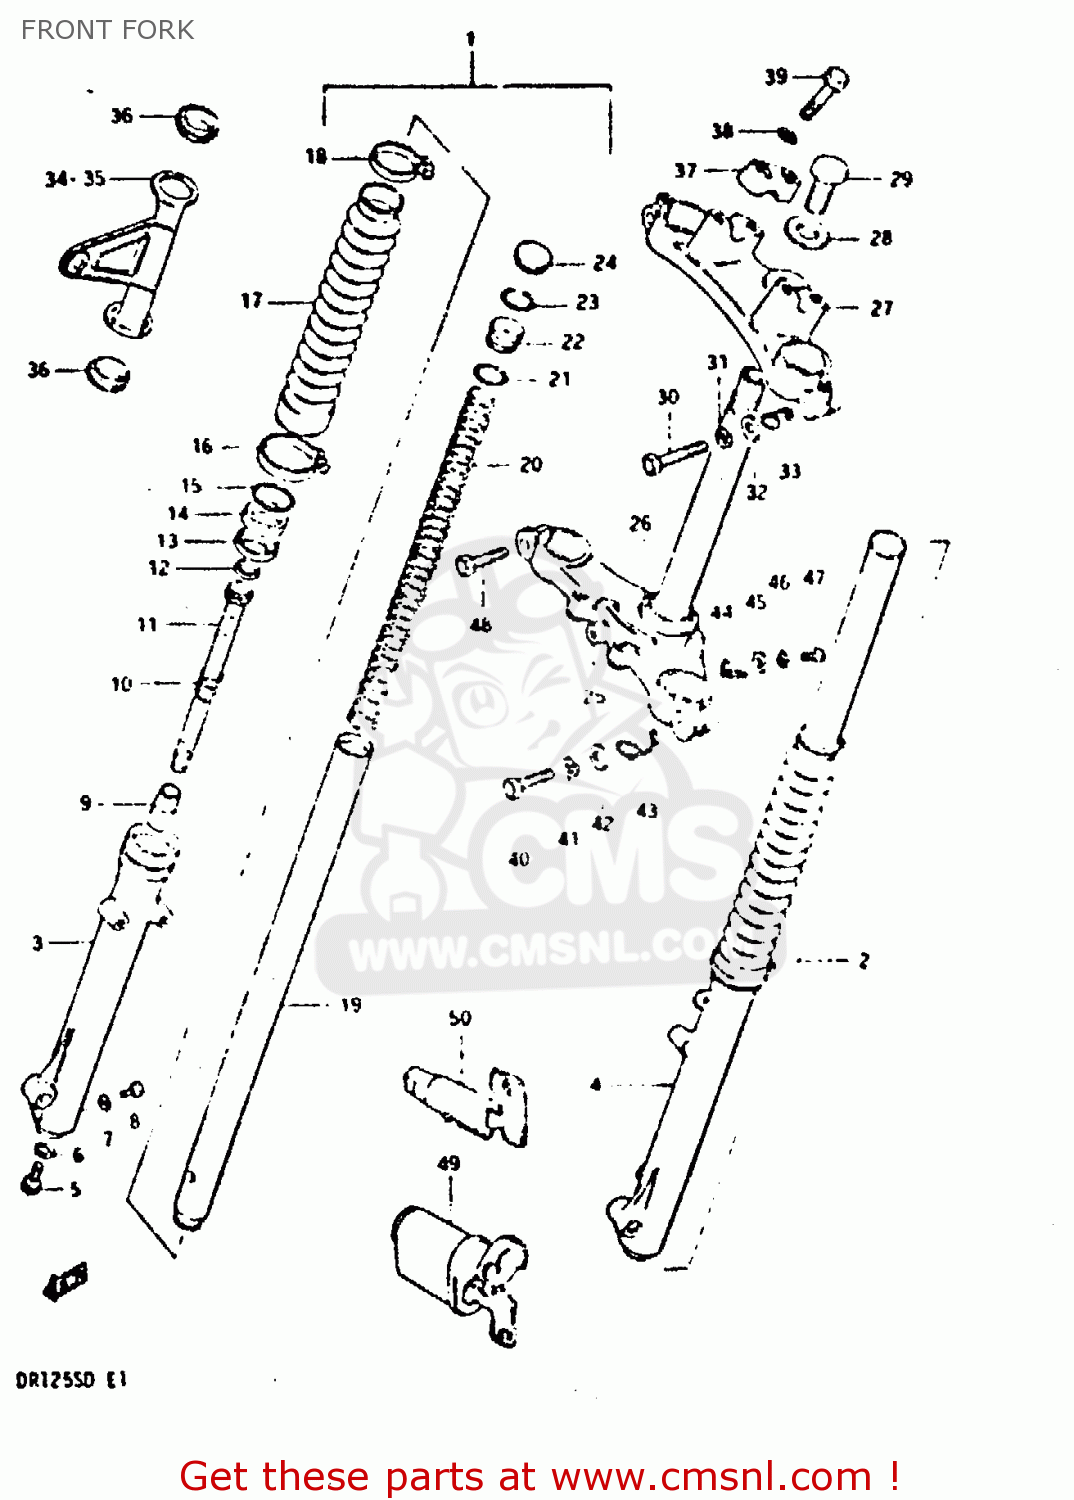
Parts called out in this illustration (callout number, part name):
1	DAMPER ASSEMBLY,RIGHT
2	DAMPER ASSEMBLY,LEFT
3	TUBE,FORK,OUTER,RIGHT
4	TUBE,FORK,LEFT,OUTER
5	BOLT(8X27)
6	GASKET (NAS)
7	GASKET,DRAIN,PLUG (NAS)
8	BOLT
9	PIECE,OIL LOCK
10	SPRING,REBOUND
11	CYLINDER,FRONT FORK
12	RING, PISTON
13	SPACER
14	OIL SEAL,FRONT FORK
15	CIRCLIP,FORK OIL SEAL
16	CLAMP
17	BOOT
18	BAND
19	TUBE,FORK,INNER
20	SPRING,FRONT FORK
21	O RING
22	SEAT,SPRING
23	RING,STOPPER
24	CAP,FRONT FORK
25	STEM, STEERING
26	RACE,STEERING OUTER LWR
27	HEAD,STEERING STEM
28	WASHER,STEM HEAD(10.5X30X3.2)
29	BOLT,FORK INNER TUBE
30	BOLT
31	LOCK WASHER
32	WASHER
33	GUIDE,CABLE
34	BRACKET,HEADLAMP,RIGHT
35	BRACKET,HEADLAMP,LEFT
36	CUSHION,HEADLAMP BRACKET
37	HOLDER,HANDLEBAR
38	LOCK WASHER
39	BOLT,HANDLE HOLDER
40	BOLT 12X45
41	WASHER,LOCK 12
42	WASHER
43	CLIP,CABLE
44	CLIP
45	WASHER
46	LOCK WASHER
47	SCREW 6X12
48	BOLT
